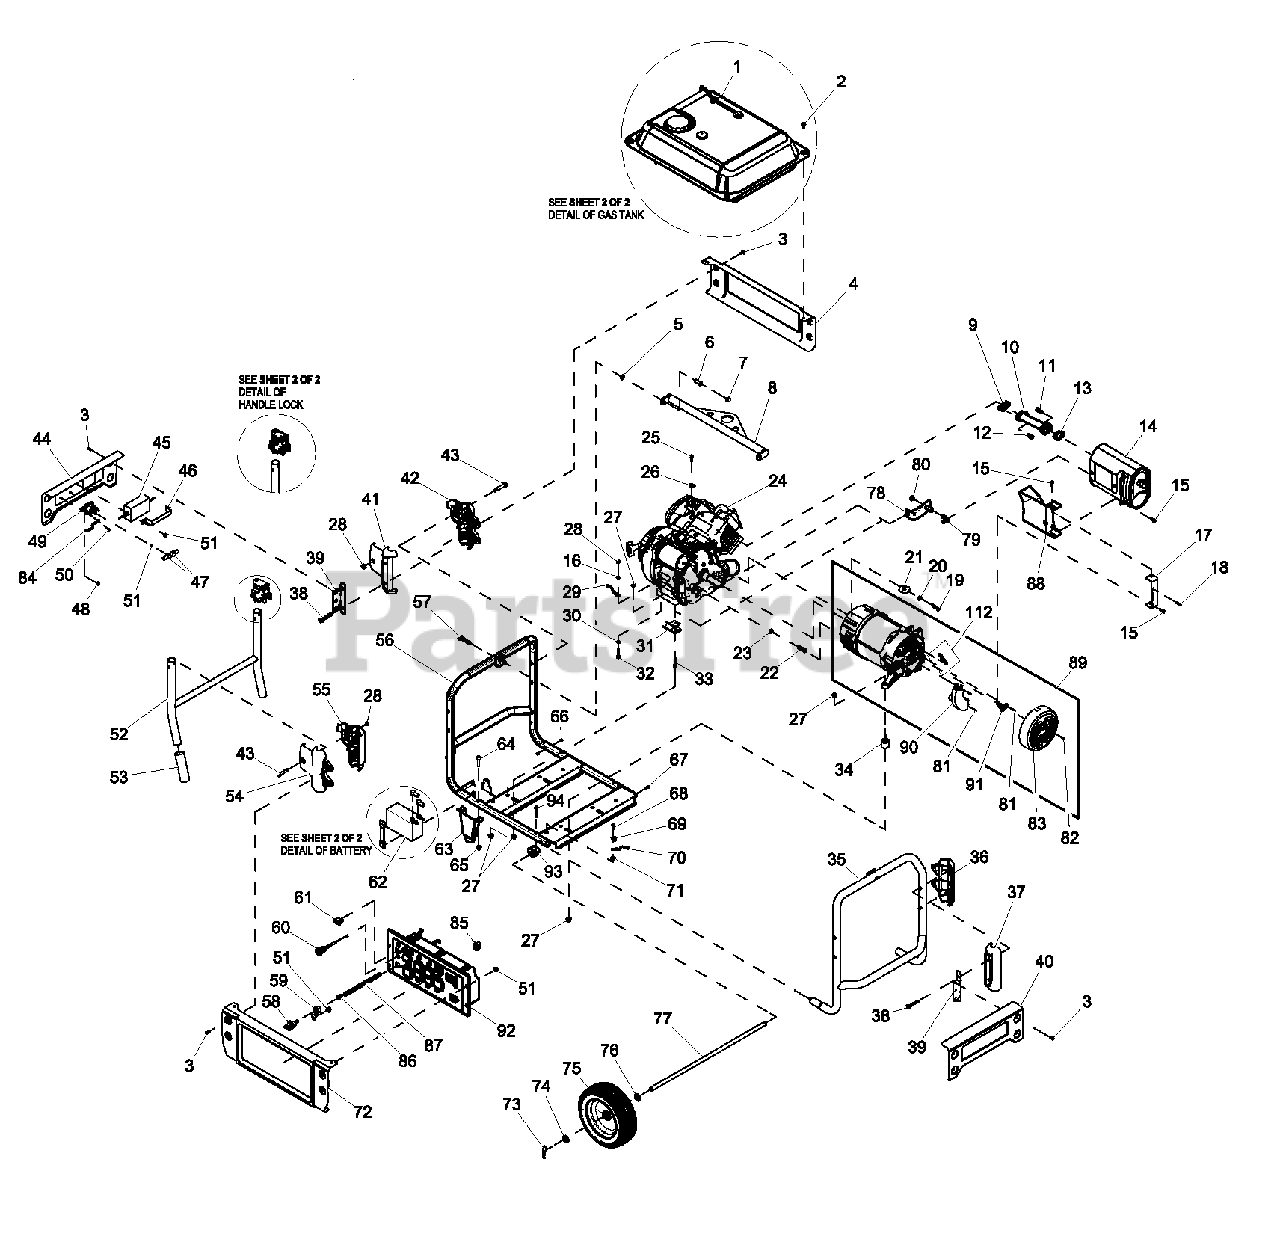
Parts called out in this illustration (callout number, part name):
1	ASSY FUEL TANK 9 GAL XP CARB
2	SCREW TTH M8-1.25 X 20
3	SCREW SWT 1/4-20 X 5/8 W/W
4	PANEL SIDE XP RAW
5	WASHER NYLON .50 X .87 X .06
6	BUSHING,FLANGED HEAD
7	NUT HEX LOCK M8-1.25 NY INS
8	ASSY LIFTING BEAM XP6.5-8 RAW
9	GASKET, EXHAUST
10	MANIFOLD 410CC
11	SCREW SHC M8-1.25X25 PAT BLK
12	SCREW SHC M8-1.25 X 20 C12.9
13	GASKET,EXHAUST PORT
14	ASSY MUFFLER GTH530
15	SCREW SHC M8-1.25 X 20 SEMS
16	WASHER FLAT M8 SS
17	WLDMNT MTG MUFFLER ALT SIDE
18	SCREW HHFC M6-1X25 8.8 W/PATCH
19	SCREW HHC 5/16-24 X 1-1/4 G5
20	WASHER LOCK M8-5/16
21	BRACKET, MOUNTING, ALT 7KW
22	SCREW HHC 3/8-16 X 1-1/4 G5
23	WASHER LOCK M10
24	ENGINE GH410 XP 2010 IDL CNTRL
25	SCREW HHC SHLDR M5-0.8X20 G8.8
26	CLAMP, 3/16" COATED CABLE
27	NUT HEX FL WHIZ M8-1.25
28	NUT HEX M8-1.25 G8 CLEAR ZINC
29	WIRE ASSY FRAME TO BATT-NEG
30	WASHER LOCK M8 SS
31	VIBRATION MNT 45 ANGLE 65 DURO
32	SCREW HHC M8-1.25 X 40 C8.8
33	SCREW SHC M8-1.25 X 40 C8.8
34	VIB MNT 25 X 31.8 X M8-1.25
35	WELD CRADLE ALT END RAW
36	CORNER SUPPORT - OUTER XP PORT
37	CORNER SUPPORT - INNER XP PORT
38	SCREW HHFC M8-1.25X60 C8.8 ZP
39	BRACKET END PANEL
40	PANEL END XP RAW
41	CORNER HANDLE SUPT-LFT INNER
42	CORNER HANDLE SUPT-LFT OUTER
43	SCREW SHSH M8-1.25 X 40
44	WELD END PANEL XP RAW
45	BATTERY CHARGER 13.4VDC 2.5A
46	BRKT HOLD DOWN BATT CHRGR
47	BOOT, VINYL STARTER-SOLENOID
48	NUT HEX LOCK 1/4-20 NY INS
49	CONTACTOR, STARTER SOLENOID
50	NUT HEX LOCK #8-32 NY INS BRS
51	NUT HEX FL WHIZ M6-1.0
52	WELD HDL H-STYLE FOLD DOWN RAW
53	GRIP HANDLE FOAM
54	CORNER HANDLE SUPT-RT OUTER
55	CORNER HANDLE SUPT-RT INNER
56	WELD CRADLE ENGINE END RAW
57	CURVED HEAD M8-1.25 X 60MM LNG
58	VALVE, FUEL SHUT OFF
59	MTG FUEL VALVE RETAINER
60	CABLE CHOKE PORT NOM 465
61	SWITCH SPDT (ON)-OFF-ON 20A
62	BATTERY 12V10AH SEALED
63	FOOT ASSY XP
64	SCREW HHFC M8-1.25 X 45
65	NUT HEX FL WHIZ M8-1.25
66	PLUG PLASTIC 0.312
67	SCREW HHSD 1/4-14 X 7/8 BZ
68	SCREW HHTT M6-1.0 X 25 ZINC
69	LUG SLDLSS #2-#8 X 17/64 CU
70	GRND WIRE PORT BRG CARR-FRAME
71	WASHER LOCK SPECIAL 1/4"
72	WELD PANEL SIDE C-PNL XP RAW
73	COTTER HAIRPIN 2.56 X .80
74	WASHER FLAT 5/8 ID X 0.039"THK
75	10" WHEEL OFFSET HUB
76	WASHER FLAT 5/8 ZINC
77	AXLE 15.87 DIA X 684 CLR ZINC
78	WLDMNT SUPPORT MUFFLER
79	J-BOLT MUFFLER M8-1.25
80	NUT TOP LOCK FL M8-1.25
81	SCREW HHFC M5-0.8 X 16
82	SCREW HHFC M5-0.8 X 12
83	COVER ALTERNATOR INLET 5-7KW
84	WIRE, JUMPER,SOL COIL-CONTACT
85	CLIP SNAP-IN WIRE MANAGEMENT
86	CLAMP HOSE BAND .41
87	FUEL HOSE, 160 MM LONG
88	WLDMNT MTG MUFFLER HEAT SHIELD (6500W UNITS)
89	ALT 6500W SAE BT COP-AL VN (6500W UNITS)
90	AVR 5.5-7.5KW VISION ALT (6500W UNITS)
91	ASSEMBLY,BRUSH VISION (6500W UNITS & 8000W UNITS)
92	ASSY C-PNL 6.5KW XP (6500W UNITS)
93	AXLE MNT RAW
94	SCREW HHFC M6-1X50 8.8 W/PATCH
